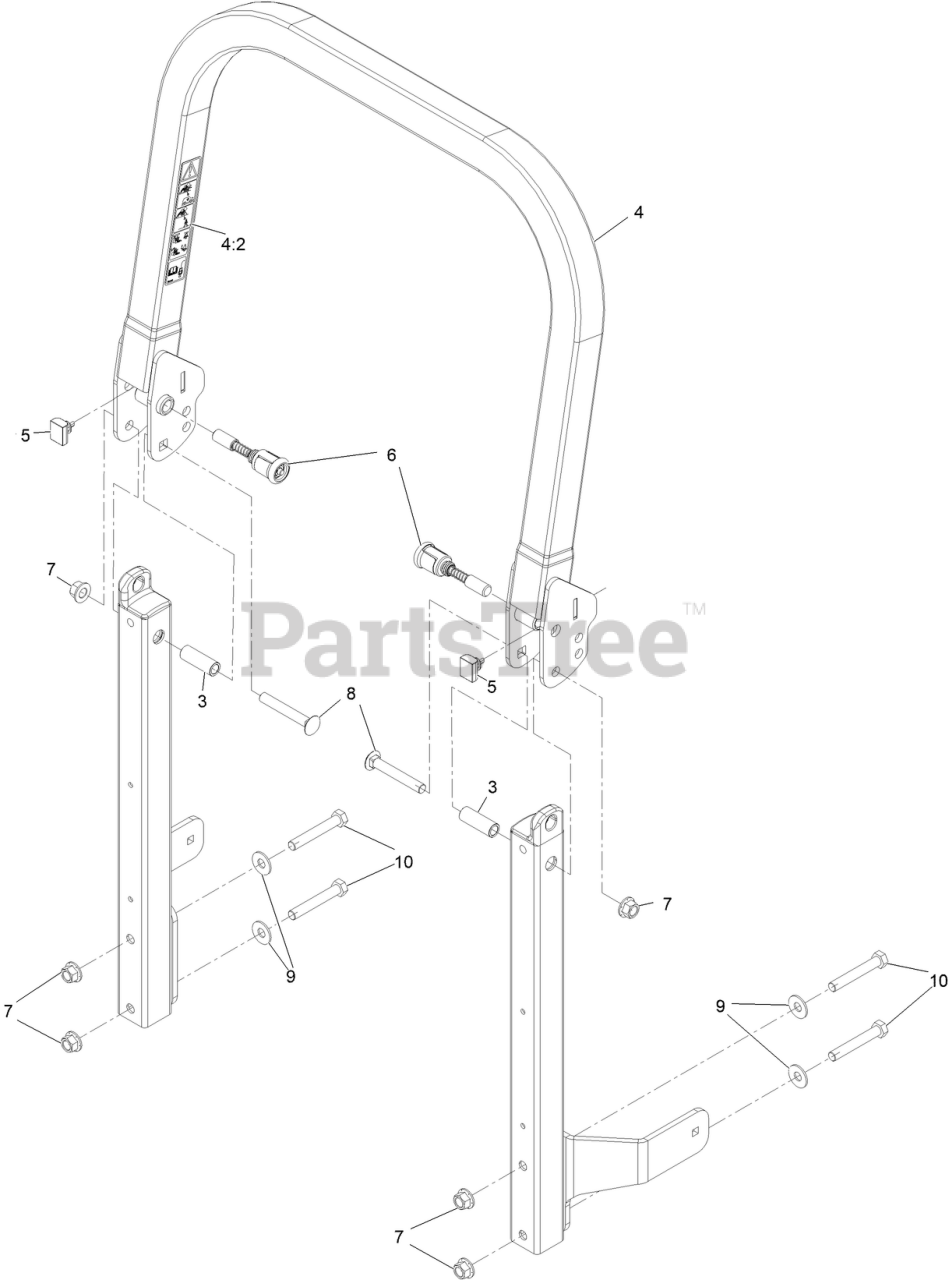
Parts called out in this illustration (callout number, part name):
4	Upper ROPS ASM
4:2	DECAL-WARNING
5	BUMPER-ROPS
6	PIN-SPRING
7	Nut-Lock 1/2-13
8	SCREW-CARR
9	WASHER-SPRING
10	SCREW-HH
